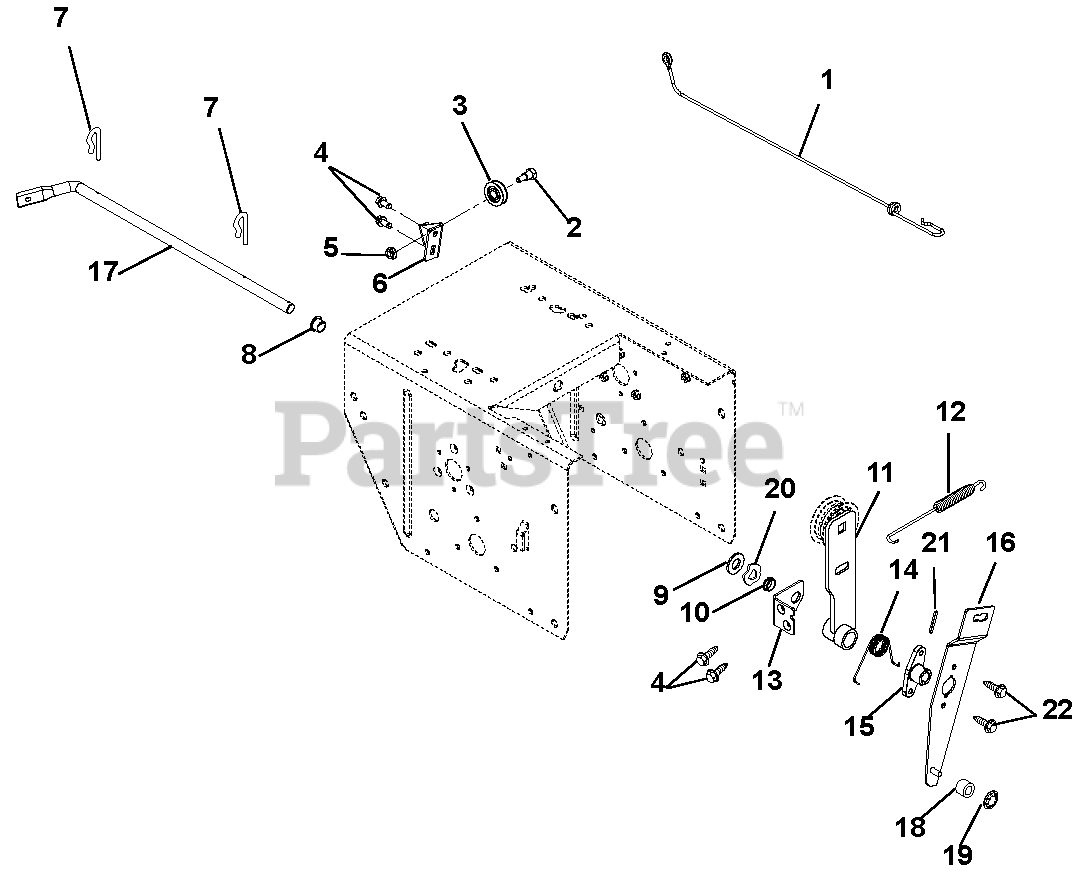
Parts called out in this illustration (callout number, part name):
1	CABLE, LOWER TRACTION,SS & PRO
2	BOLT, SHLDR-.375X.375X.25-20
3	PULLEY, CABLE
4	SCR-TAP .25-20X.50 HWH TR YWZ
5	@NUT-LK-TOP-FLG .25-20 YWZC
6	BRACKET, CABLE PULLEY
7	CLIP, SPRING
8	BUSHING, POLYLINER-.50 SPLIT
9	@WSHR-FL-STL.531X1.06X.095YWZC
10	BUSHING, POLYLINER-.50 SNAPIN
11	ARM, IDLER-TRACTION
12	SG-TENS .06X.482X5.35
13	BRACKET, SUPPORT
14	SG-TORS .067X.88
15	HUB, BRAKE ARM
16	ARM, IDLER-ATTACHMENT
17	ARM, ATTACHMENT
18	BSHG,SLV .265 X .625 X .375
19	RG-RTNG-EXT .250X.010
20	WAVE WASHER .531X.781X.125FH
21	PIN-ROLL .125X1.00
22	SCR-TAP .25-20X.75 HWH TR YWZ
